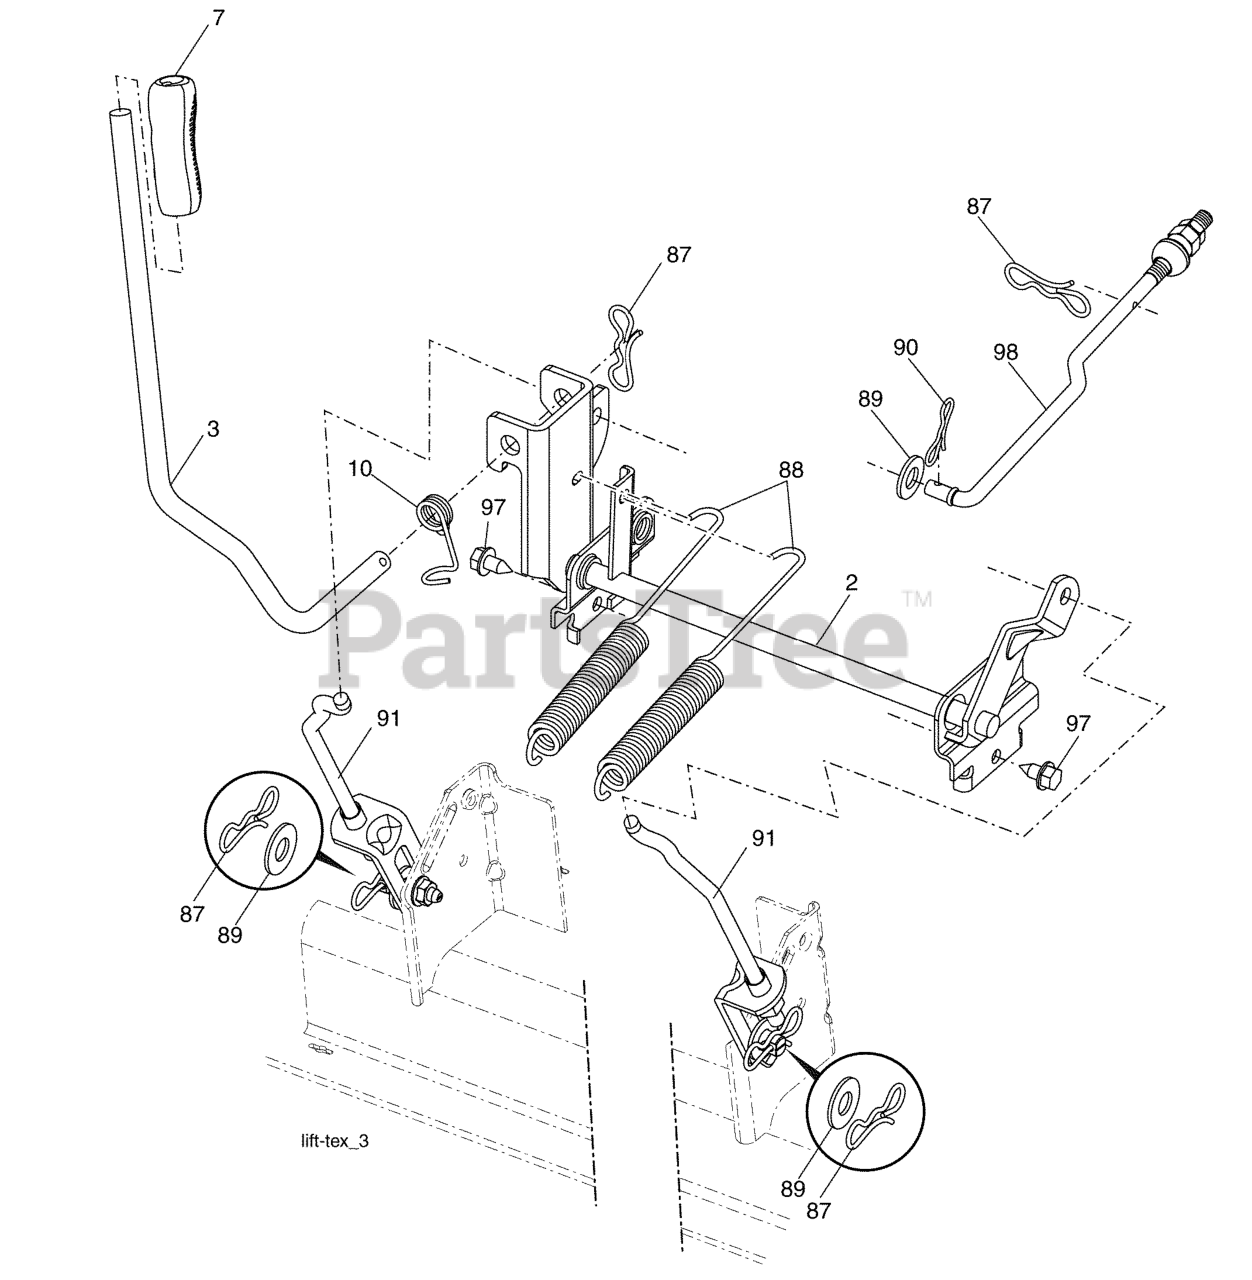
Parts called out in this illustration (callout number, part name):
2	SHAFT.ASM.LIFT.CROSS.H
3	LEVER.LIFT.HANDLE.LT
7	GRIP.HANDLE.LIFT.PVC.BLACK
10	SPRING.TORSION.LIFT.HANDLE
87	PIN.COTTER.7/16.BOW TI.
88	SPRING.LIFT.ASSIST
89	WASHER.CLEAR.ZINC
90	PIN.COTTER.5/16.BOW TI
91	LINK.ASM.LIFT.REAR
97	SCREW, 3/8-16X3/4
98	LINK.ASM.SUSP.FRONT.MWR.10.5
